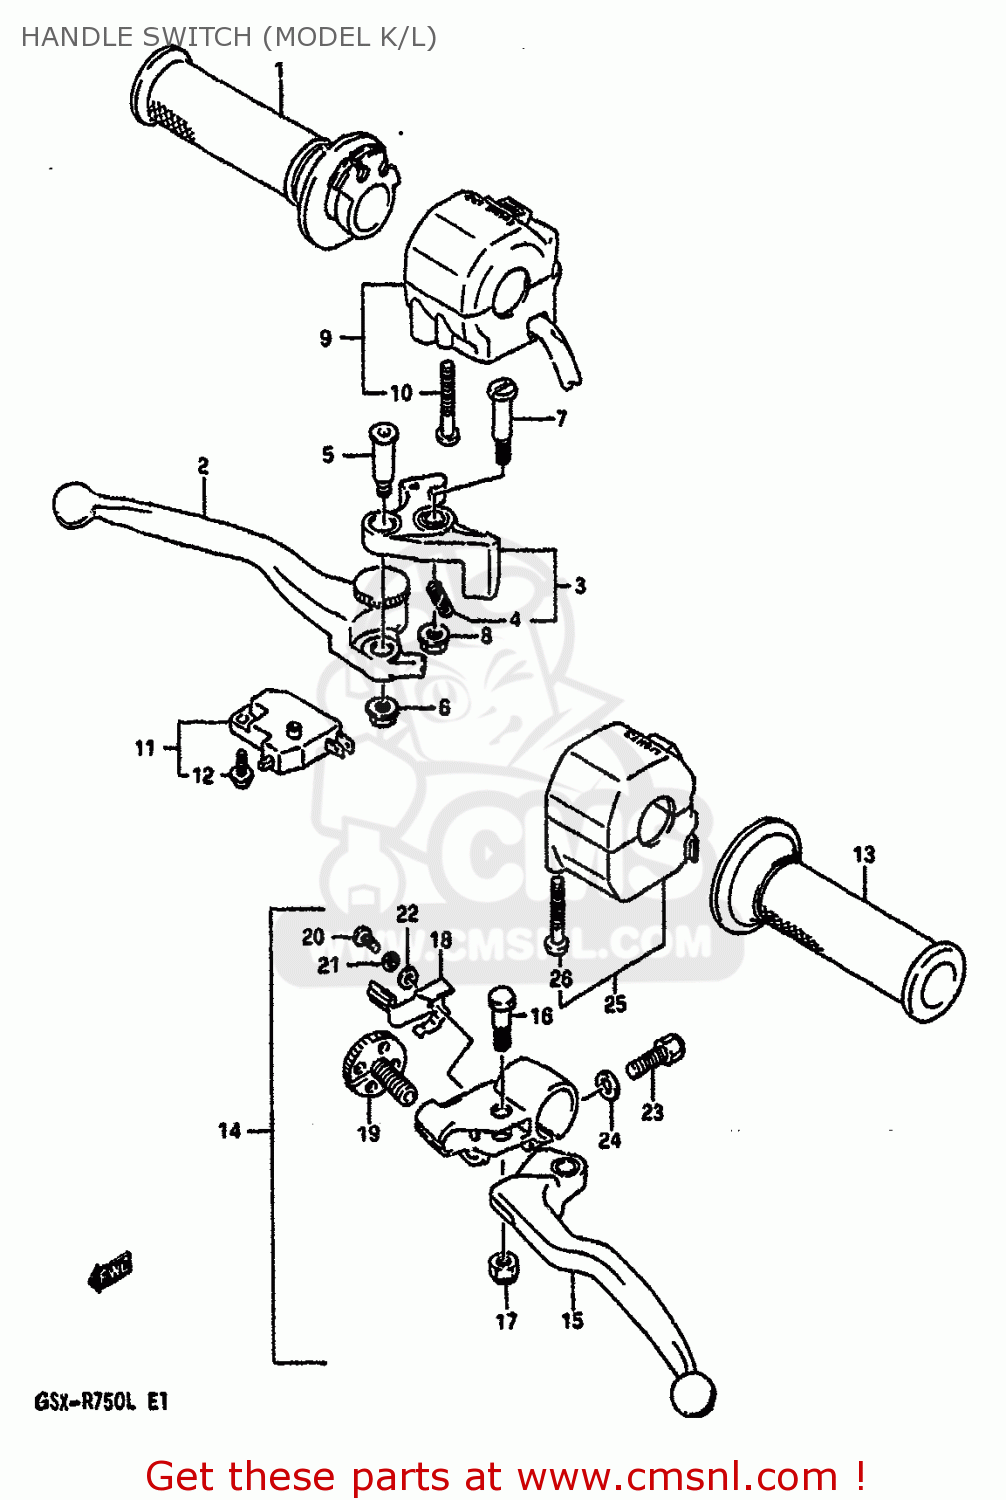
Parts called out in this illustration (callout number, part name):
1	GRIP,THROTTLE
2	LEVER,ADJUST
3	KNOCKER
4	SPRING
5	BOLT,LEVER
6	NUT
7	BOLT,LEVER PIVOT
8	NUT 6MM
9	SWITCH ASSY,HANDLE RH
10	SCREW, 5X45
11	SWITCH ASSEMBLY,STOP
12	SCREW
13	GRIP,L
14	LEVER ASSY,CLUTCH
15	LEVER,CLUTCH
16	BOLT,LEVER PIVOT
17	NUT
18	ADJUST,SPRING
19	ADJUSTER,LOCK
20	SCREW
21	LOCK WASHER
22	WASHER
23	BOLT
24	WASHER
25	SWITCH,HANDLE,
26	SCREW, 5X45
